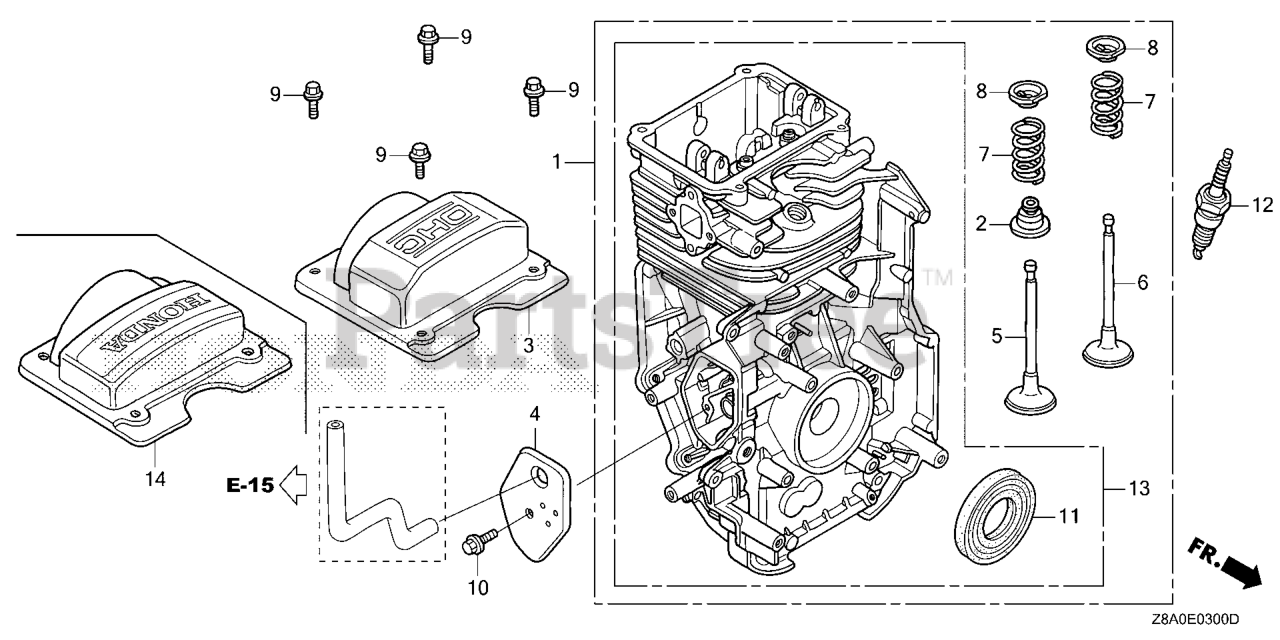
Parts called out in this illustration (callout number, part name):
2	SEAL, VALVE STEM
4	COVER, BREATHER (Honda Code 5580006). (BREATHER VALVE ASSY.)
5	VALVE, IN. (TECHNOSTAR)
6	VALVE, EX. (L8E)
6	VALVE, EX. (C8E)
7	SPRING, VALVE
8	RETAINER, VALVE SPRING
9	BOLT, FLANGE (6X12) (CT200)
10	BOLT, FLANGE (6X14)
11	OIL SEAL (25.4X62X6)
12	SPARK PLUG (BPR6ES) (NGK)
13	CYLINDER ASSY. (NOT AVAILABLE. USE ALTERNATE PART 12000-Z0L-940.)
13	CYLINDER ASSY.
14	COVER, CYLINDER HEAD
